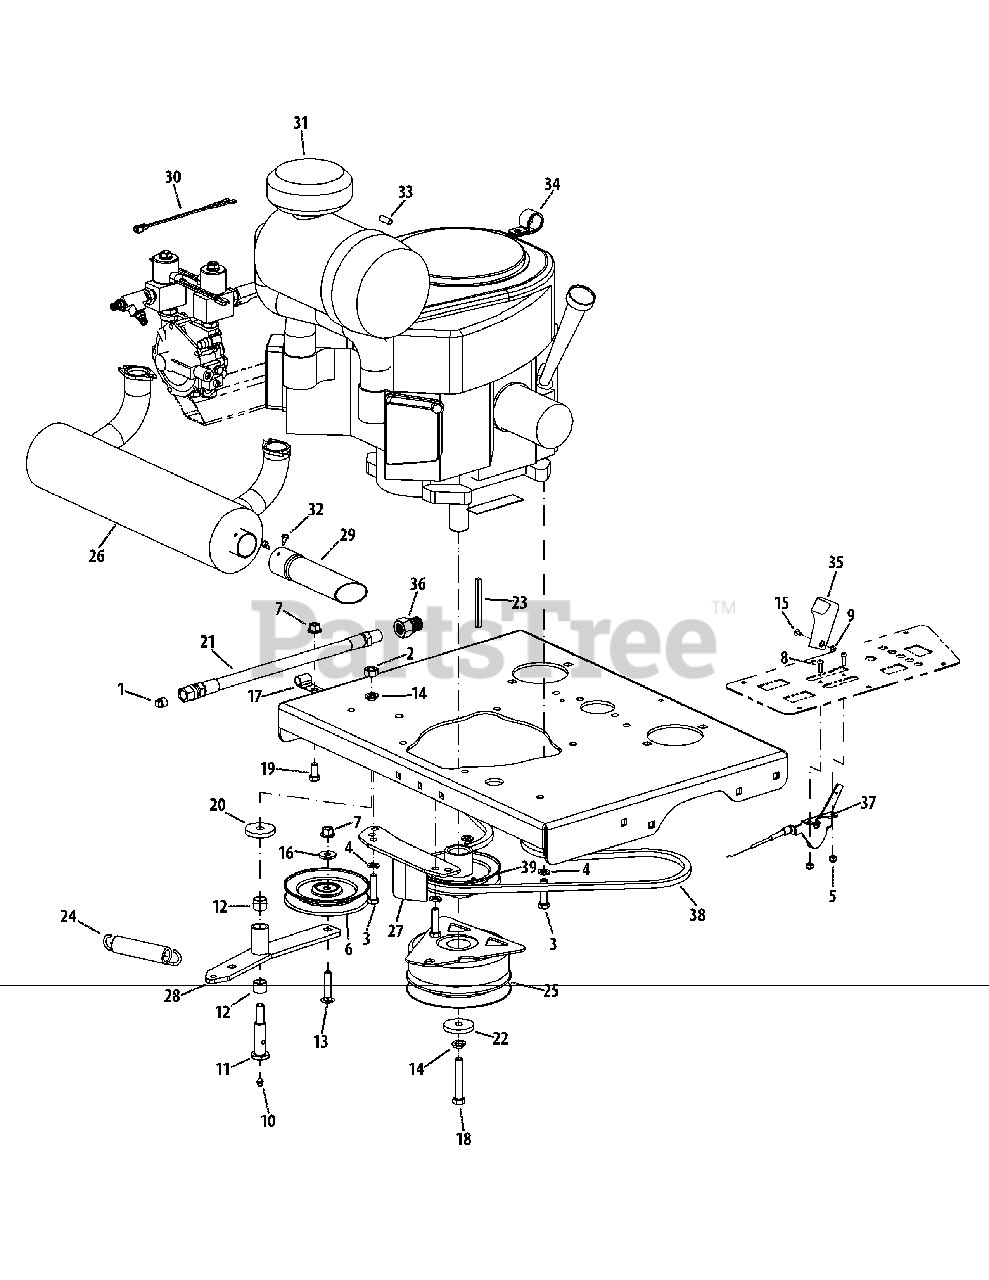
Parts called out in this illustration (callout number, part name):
1	Pipe Plug, 3/8
2	Nut, 7/16
3	Hex Screw, 3/8-16 x 1.50
4	Lock Washer, .375 x .680 x .100
5	Nut, #10-32
7	Flange Counter Lock Nut, 3/8-16
8	Machine Screw, #10-32 x .625
9	Nut, #8-32
10	Grease Fitting, 1/4-28
11	Shoulder Bolt, .625 x 1.95
12	Sleeve Bearing, .628 x .753 x.625
13	Carriage Bolt, 3/8-18 x 1.75
14	Lock Washer, .490 x .776 x .114
15	Machine Screw, #8-32 x .356
16	Washer, .406 x 1.00 x .105
17	J-Clip, .470 x 1.80
18	Hex Screw, 7/16-20 x 2.50
19	Hex Screw, 3/8-16 x .750
20	Washer, .438 x 1.75 x .250
21	Oil Drain Hose
22	Washer, .438 x 1.745 x .250
23	Key, .250 x .250 x 3.00
24	Extension Spring, .98 x 5.0 x .140
25	Brake Clutch
27	Clutch Return Assembly
28	Idler Arm Assembly
29	Exhaust Pipe
30	LPG Engine Harness Assenbly
31	Kawasaki FXT00V-BS04-R Engine
32	Hex Washer Screw, #10-16 x .500
33	Vinyl Cap, 1/4
34	Clamp, 1.0
35	Throttle Control Knob
36	Hex Fitting, 1.0
37	Throttle Cable
39	Pump Drive Pulley
